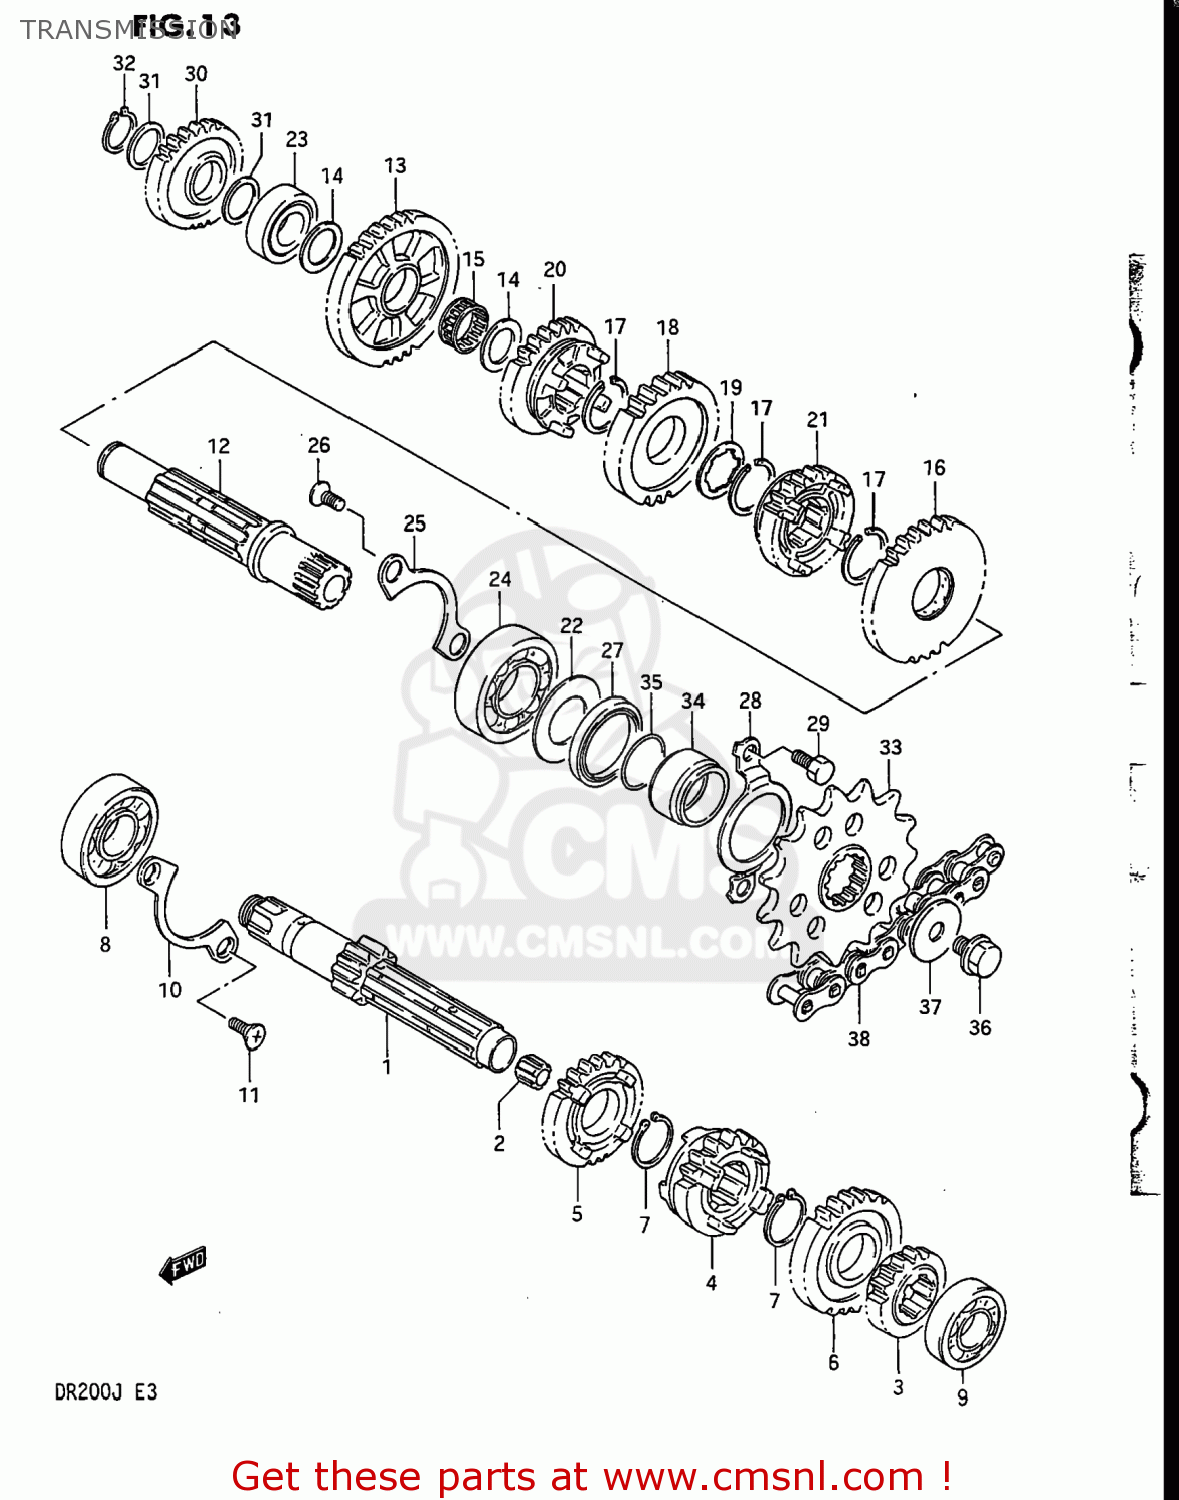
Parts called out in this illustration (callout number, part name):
1	SHAFT,COUNTER (NT:11)
2	BUSH
3	GEAR,2ND DRIVE
4	GEAR,THIRD DRIVE (NT:16)
5	GEAR,4TH DRIVE
6	GEAR,FIFTH DRIVE
7	CIRCLIP
8	BEARING
9	BEARING, LH
10	RETAINER,DRIVE SHAFT BEARING
11	SCREW
12	SHAFT COMP,DRIVE
13	GEAR,1ST DRIVEN
14	WASHER,THRUST
15	BEARING(17X21X9.8)
16	GEAR,SECOND DRIVEN (NT:29)
17	CIRCLIP
18	GEAR,THIRD DRIVEN (NT:23)
19	WASHER,LOCK
20	GEAR,FOURTH DRIVEN (NT:23)
21	GEAR,5TH DRIVEN
22	WASHER,OIL SEALING
23	BEARING(17X36X12)
24	BEARING(22X50X14)
25	RETAINER,DRIVE SHAFT BEARING
26	SCREW
27	SEAL,OIL(30X40X6)
28	RETAINER,DRIVESHAFT O
29	BOLT
30	GEAR,KICK STARTER IDLE
31	WASHER
32	CIRCLIP
33	SPROCKET,ENGINE
34	SPACER,ENGINE SPROCKET
35	O RING(D:2.5,ID:21)
36	BOLT
37	WASHER
38	CHAIN ASSEMBLY,DRIVE
